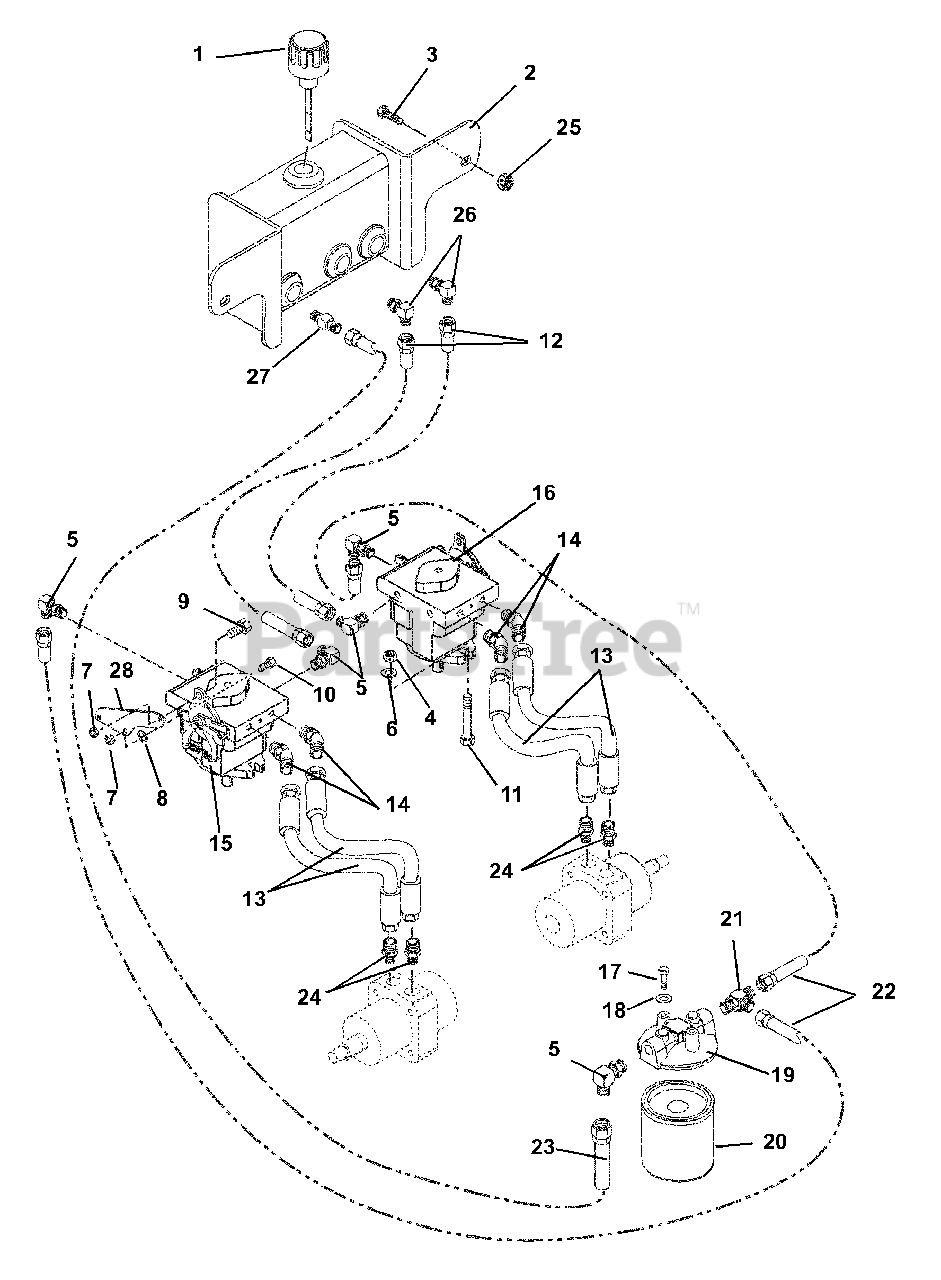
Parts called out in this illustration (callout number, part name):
1	Breather, Dipstick
2	Tank Assembly, Hydraulic
3	Bolt, Hex .38-16 x 1.00 Grade 5
4	Nut, Nylon Locking .44-14
5	Fitting, Hydraulic
6	Washer, Flat Steel .43 x 1.00 x .16
7	Nut, Locking Center .31-18
8	Bushing, Sleeve .377 x .624 x .37
9	Bolt, Hex .31-18 x 1.00 Grade 5
10	Bolt, Hex .31-18 x .50 Grade 5
11	Bolt, Hex .44-14 x 1.50 Grade 5
12	Hose, Hydraulic
13	Hose, Hydraulic
14	Fitting, Hydraulic
15	Pump, Hydraulic Right Hand w/ Return
16	Pump, Hydraulic Left Hand w/ Return
17	Bolt, Hex .25-20 x .50 Grade 5
18	Washer, Locking .25 x .062 Regular
19	Head, Filter
20	Filter, Oil
21	Fitting, Hydraulic Tee
22	Hose, Hydraulic
23	Hose, Hydraulic
24	Adapter, Face Seal 10 x 8.63 O-Ring
25	Nut, Locking Nylon .38-16
26	Hydraulic, Fitting Elbow
27	Hydraulic, Fitting Straight
28	Bracket, Return to Neutral/Damper
